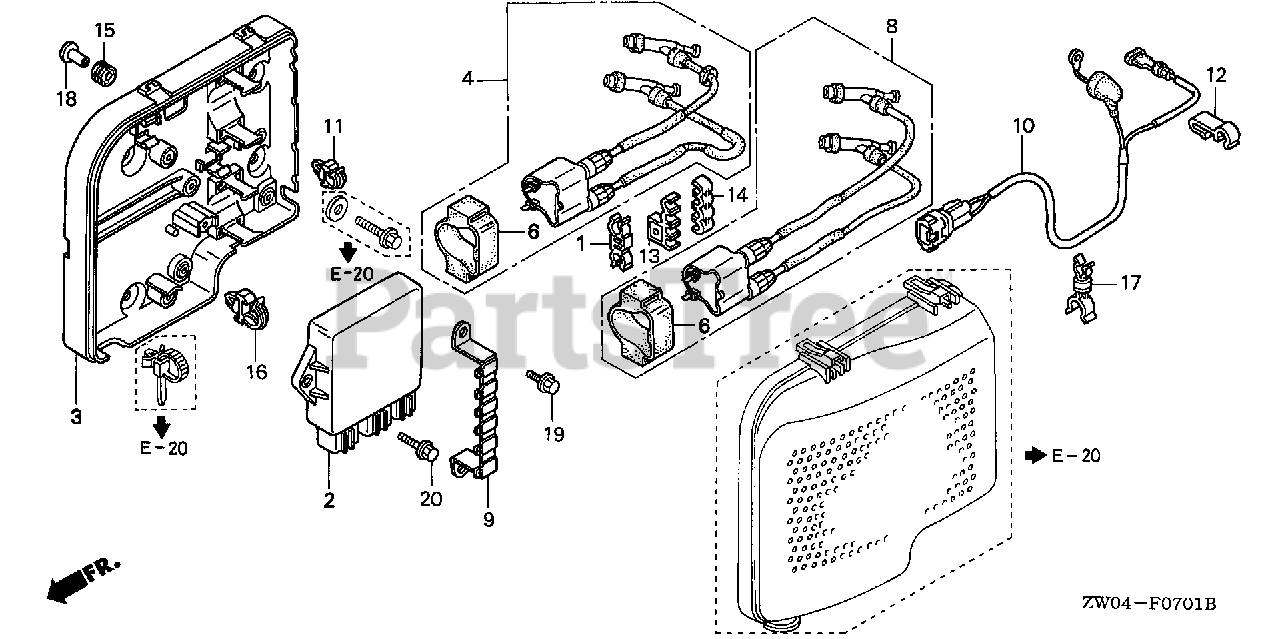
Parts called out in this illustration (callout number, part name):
1	CLAMP, R. INTERCOOLER
2	MODULE ASSY., IGNITION CONTROL (CDI)
3	CASE, IGNITION CONTROL MODULE
4	COIL ASSY., IGNITION (1)
6	SUSPENSION, IGNITION COIL
8	COIL ASSY., IGNITION (2)
9	BRACKET, CONNECTOR
10	WIRE, SWITCH
11	CLAMP, WIRE
12	CLAMP, WIRE
13	CLAMP B, IGNITION WIRE
14	GROMMET, IGNITION WIRE
14	CLAMP, IGNITION WIRE
15	GROMMET, CASE (LOWER)
16	CLIP, WIRE HARNESS
17	CLIP, SWITCH CORD
18	COLLAR, IGNITION CONTROL MODULE CASE
18	COLLAR, MODULE IGNITION CONTROL CASE (CDI)
19	BOLT, FLANGE (6X12)
20	BOLT, FLANGE (6X16)
